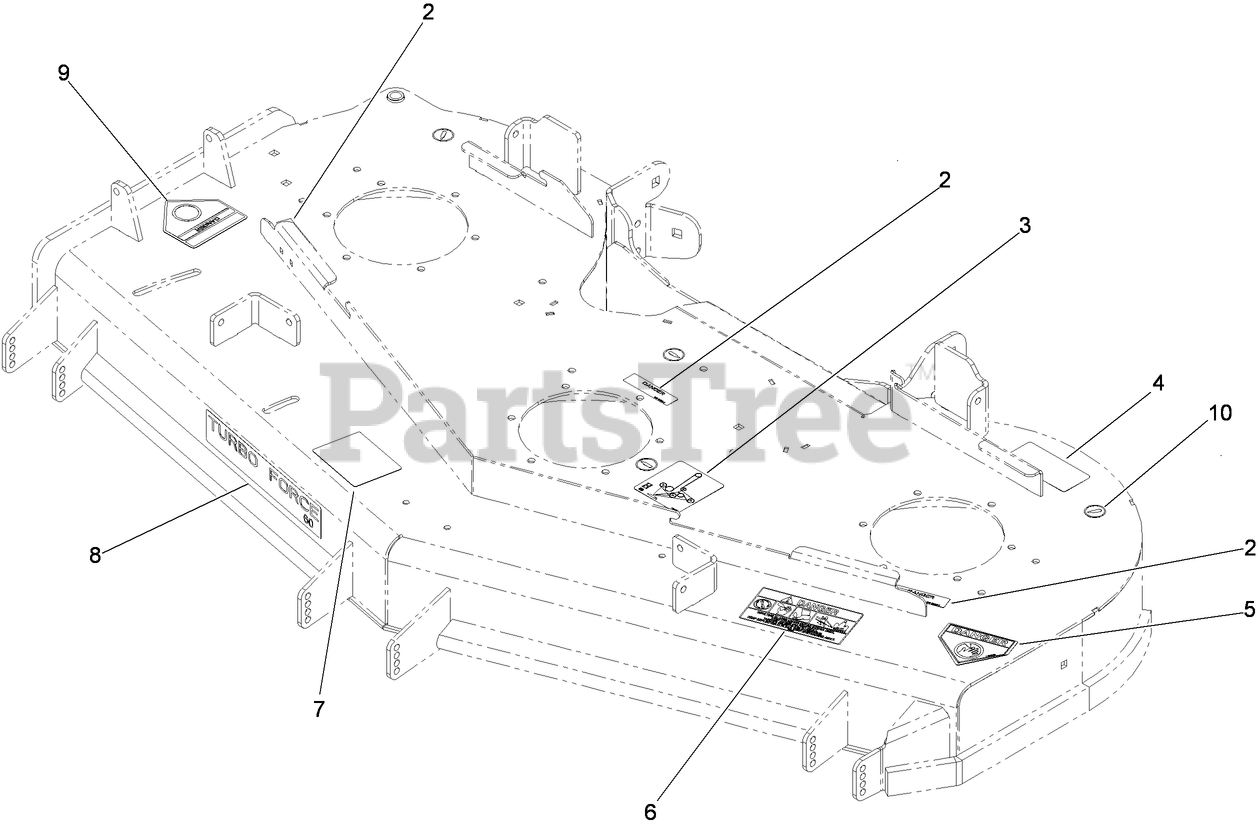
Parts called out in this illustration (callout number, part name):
2	DECAL-COVER, MISSING
3	DECAL-ROUTING, DECK BELT
4	DECAL-TORQUE
5	DECAL-DANGER
6	DECAL-DANGER, THROWN OBJECT
7	DECAL-SCALP, ANTI
9	DECAL-DANGER
10	DECAL-GREASE
